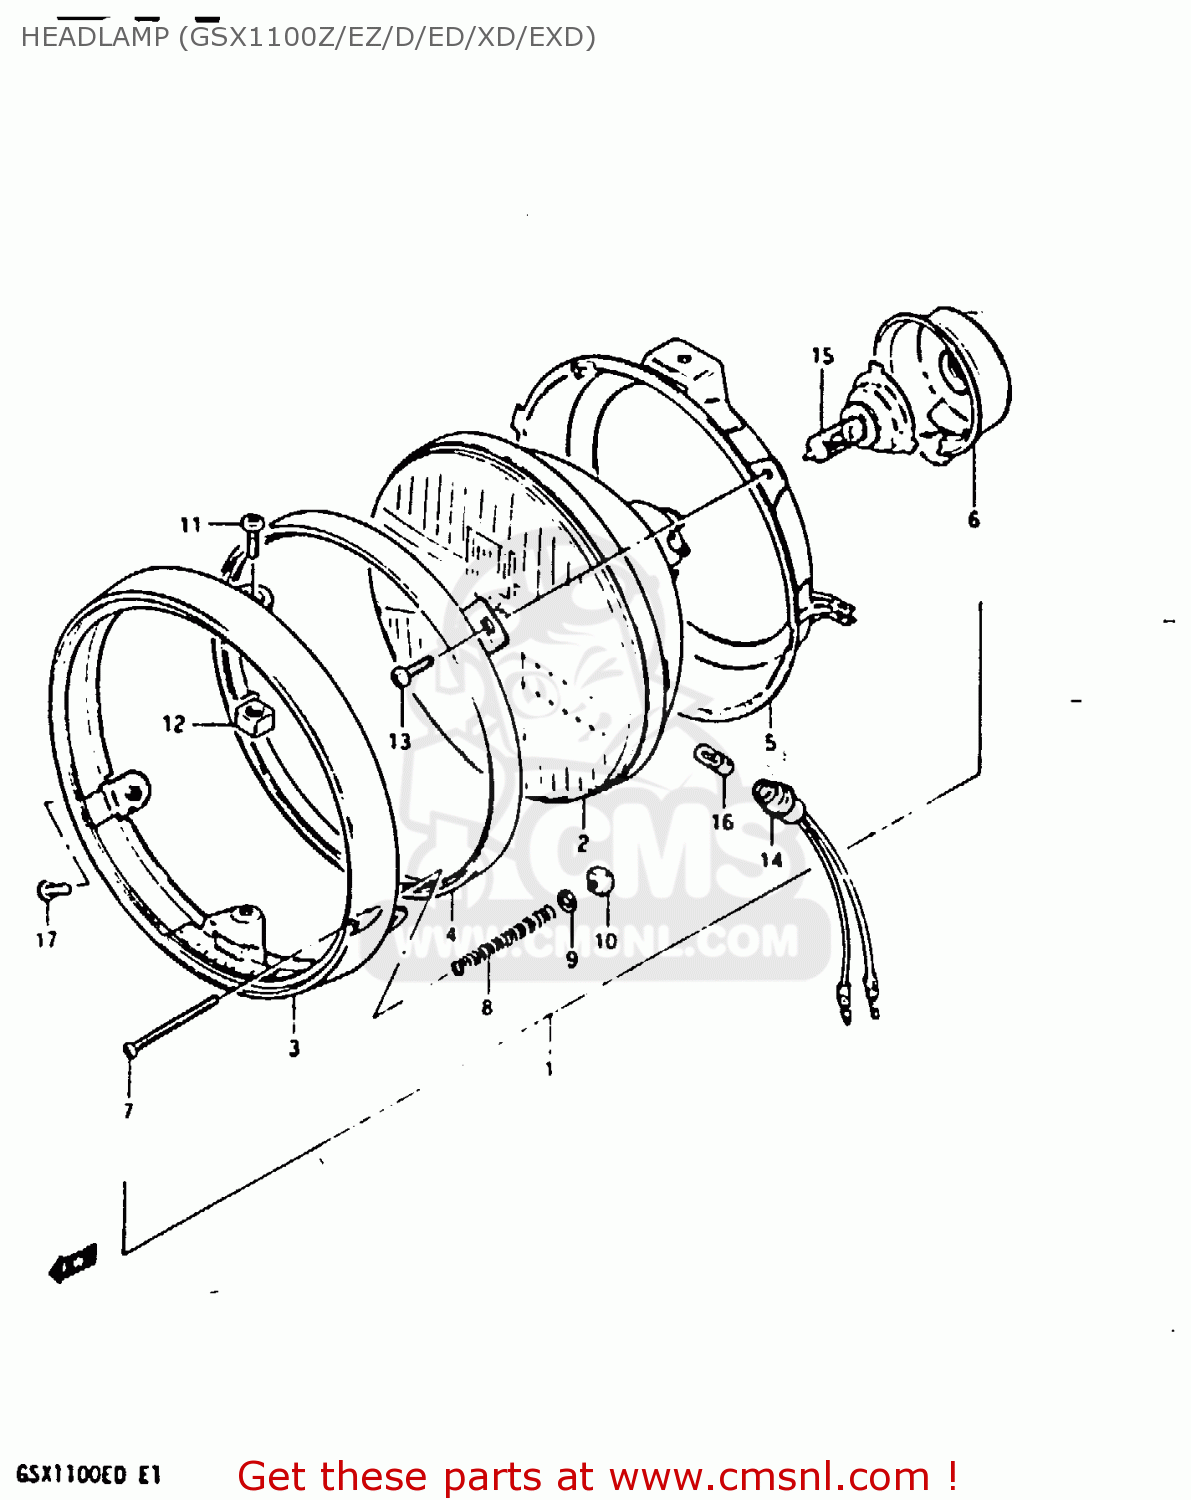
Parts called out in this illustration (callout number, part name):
1	HEADLAMP ASSY
2	UNIT
3	RIM
4	RETAINER
5	RING,MOUNTING
6	COVER,HEADLAMP SOCKET
7	SCREW
8	SPRING,HEADLAMP ADJUST
9	WASHER
10	NUT
11	SCREW
12	NUT
13	SCREW
14	SOCKET,PARKING
15	BULB(12V60/55W,H4)
16	BULB(12V4W)
17	SCREW(5X12)
